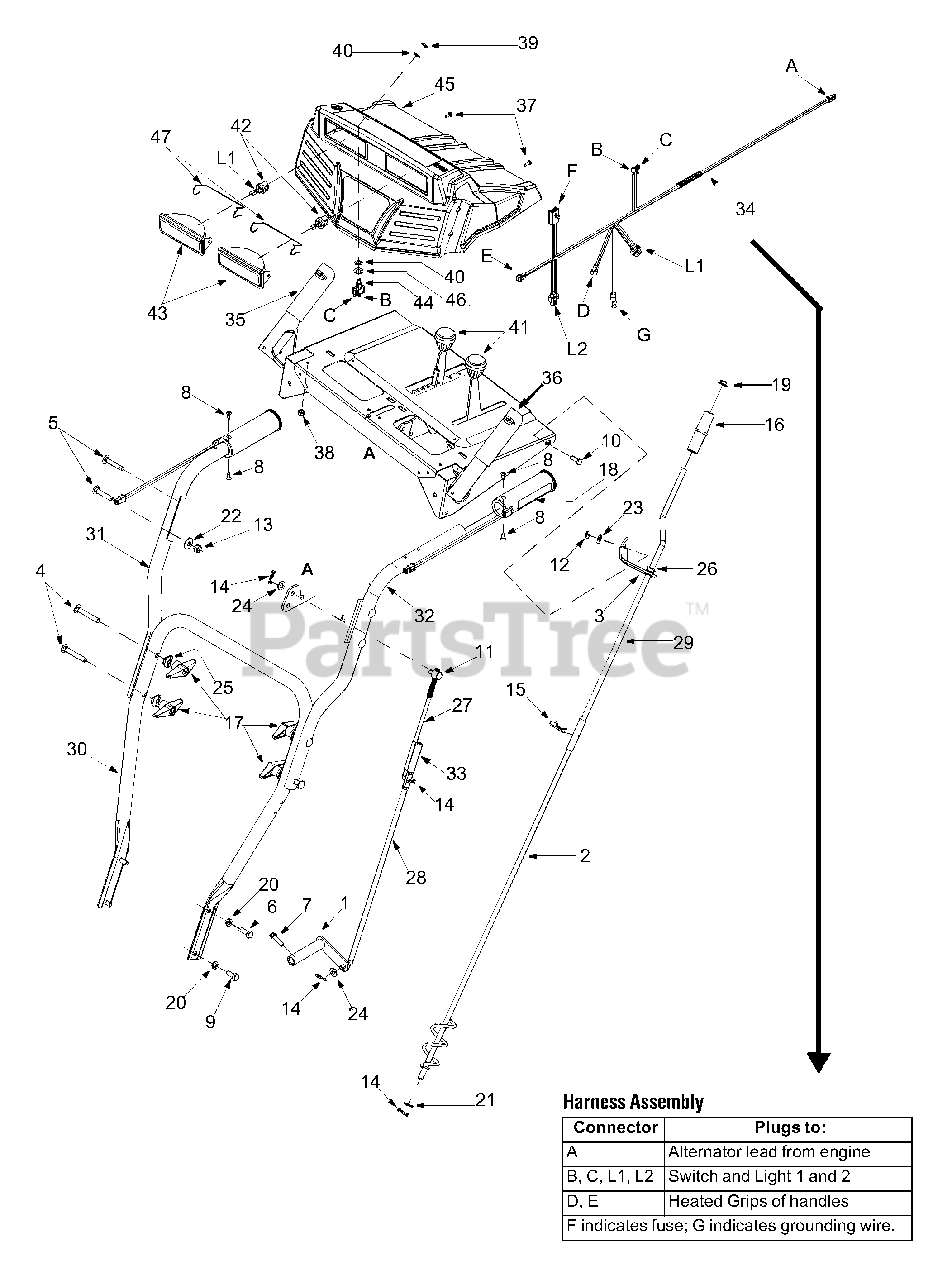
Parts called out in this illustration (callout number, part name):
4	Carriage Screw 5/16-18 x 2.25"
5	Carriage Bolt 5/16-18 x 1.75"
6	Hex Screw 5/16-18 x 1.0"
7	TT Screw 1/4-20 x 1.0"
9	Hex Screw 5/16-18 x 0.75"
10	Hex Screw 1/4-20 x 0.75"
11	Ferrule
12	Hex Nut 1/4-20
13	Lock Nut 5/16-18
14	Hairpin Clip
15	Click Pin
16	Chute Crank Knob
18	Heated Grip
20	Lock Washer
21	Flat Washer
22	Bell Washer
23	Bell Washer
24	Flat Washer
25	Saddle Washer
26	Plastic Bushing
27	Shift Rod: Upper
28	Shift Rod: Lower
34	Harness Assy.
35	Handle Engagement RH: Black
36	Handle Engagement LH: Black
37	B Screw #10-16 x 0.625"
40	Toggle Switch
41	Shift Knob
42	Halogen Lamp
43	Lamp Housing
44	Toggle Switch
45	Handle Panel
46	Flat Washer.474 x.879 x.064
47	Headlight Retainer
